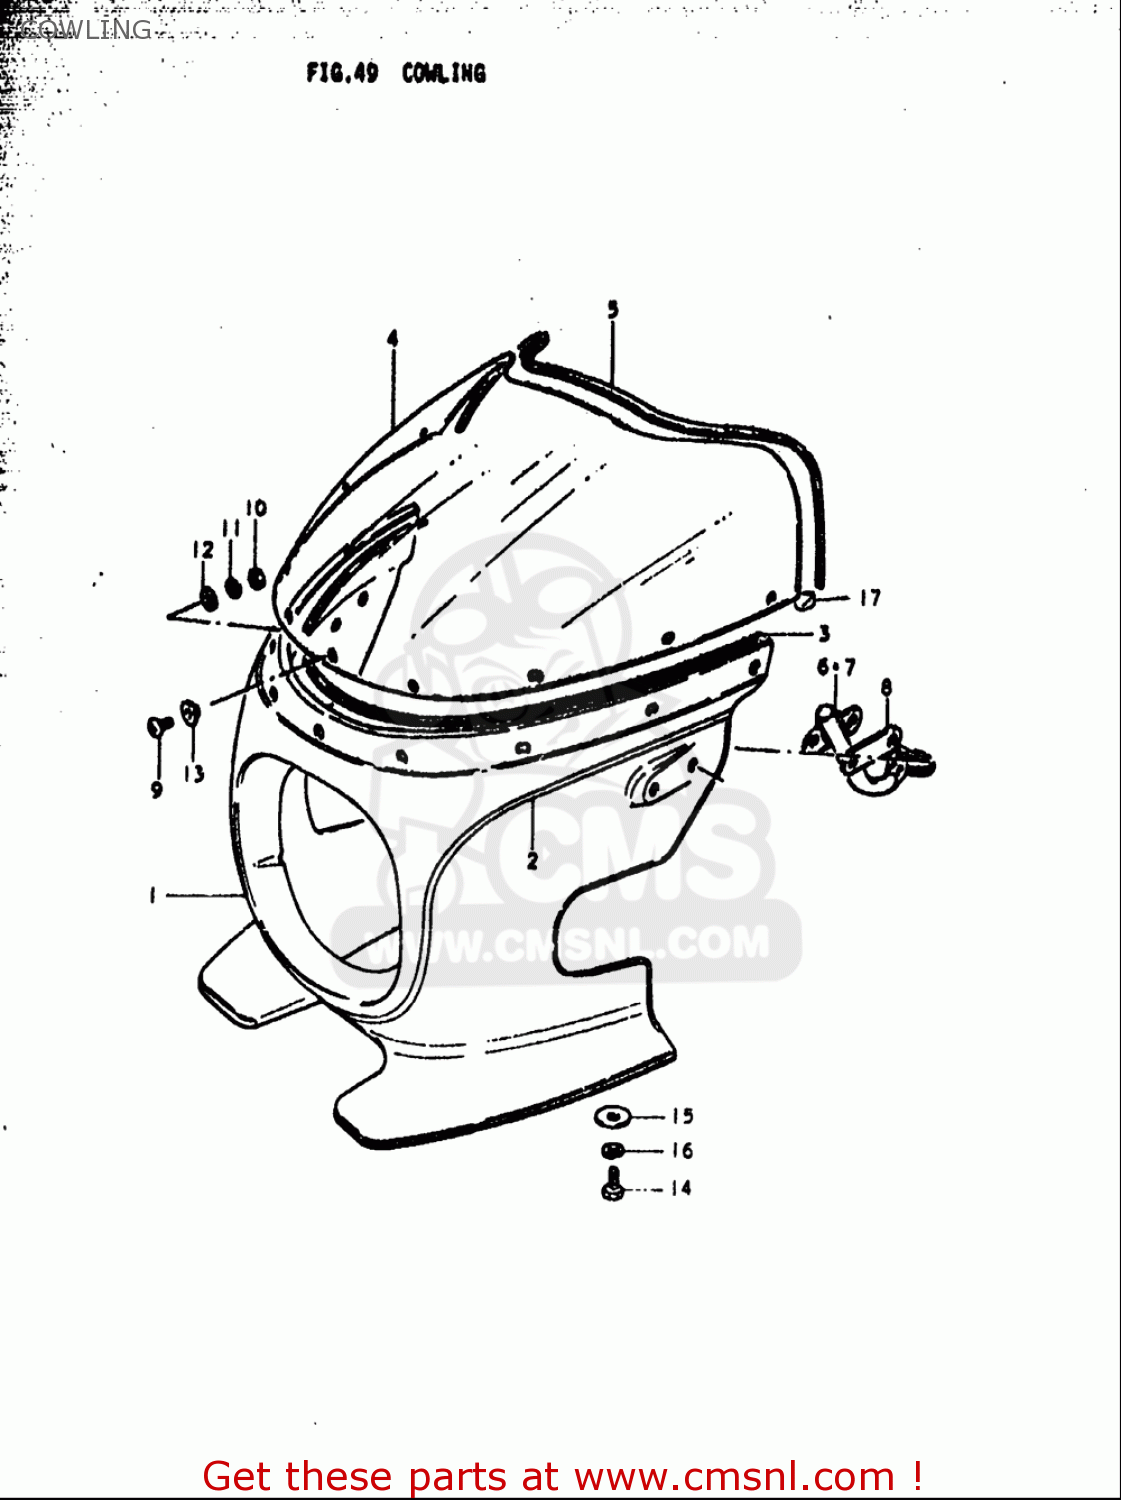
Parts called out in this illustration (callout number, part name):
3	MOLDING,COWLING
6	BRACKET,COWLING,UPPER
7	BRACKET,COWLING,UPPER
8	CUSHION,COWLING
9	SCREW
10	NUT
11	WASHER,LOCK
12	WASHER
13	CUSHION
14	BOLT
15	WASHER
16	WASHER,LOCK
17	COVER,MOLDING END
